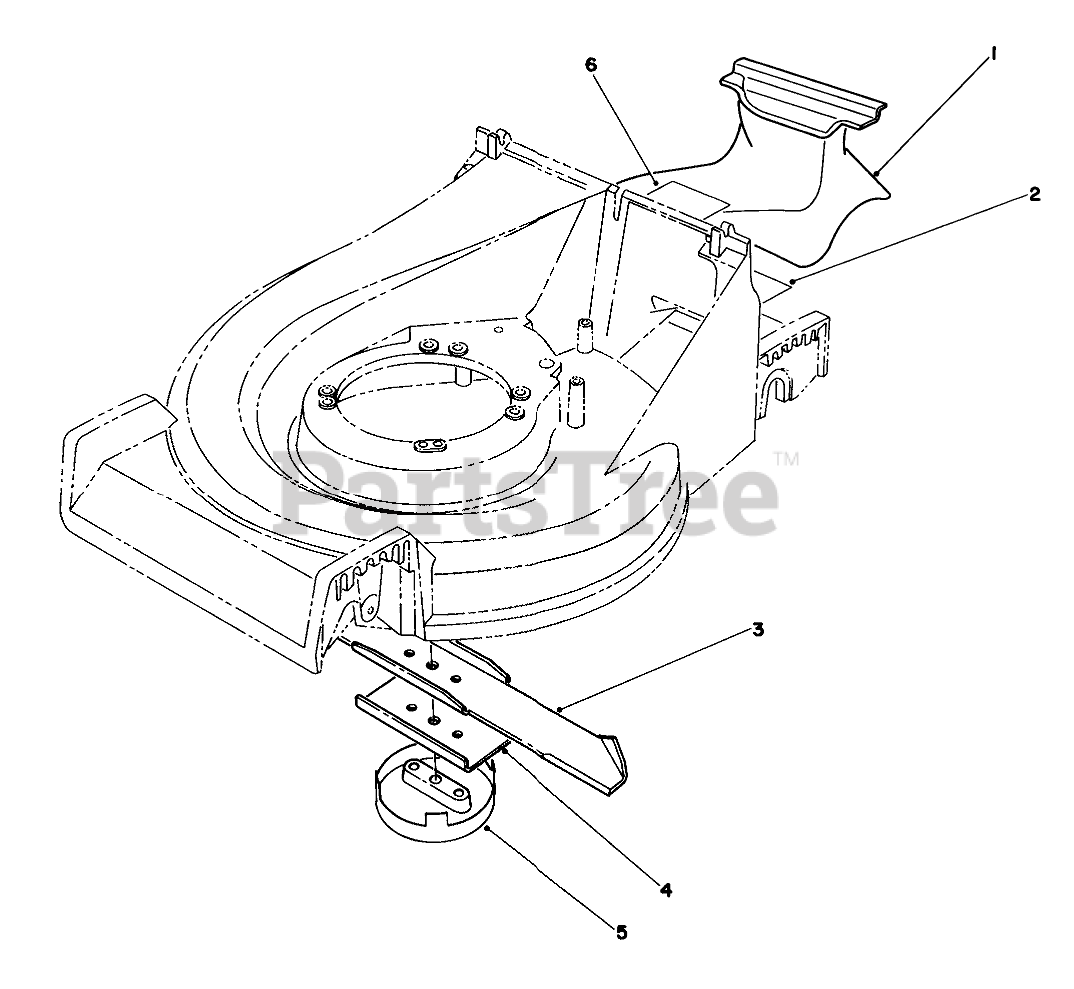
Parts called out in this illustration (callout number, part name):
1	RECYCLER PLUG
2	DECAL - MULCHER KIT
3	BLADE-21in
4	Stiffener
5	CUP-SCALP, ANTI
6	DECAL - FRENCH
